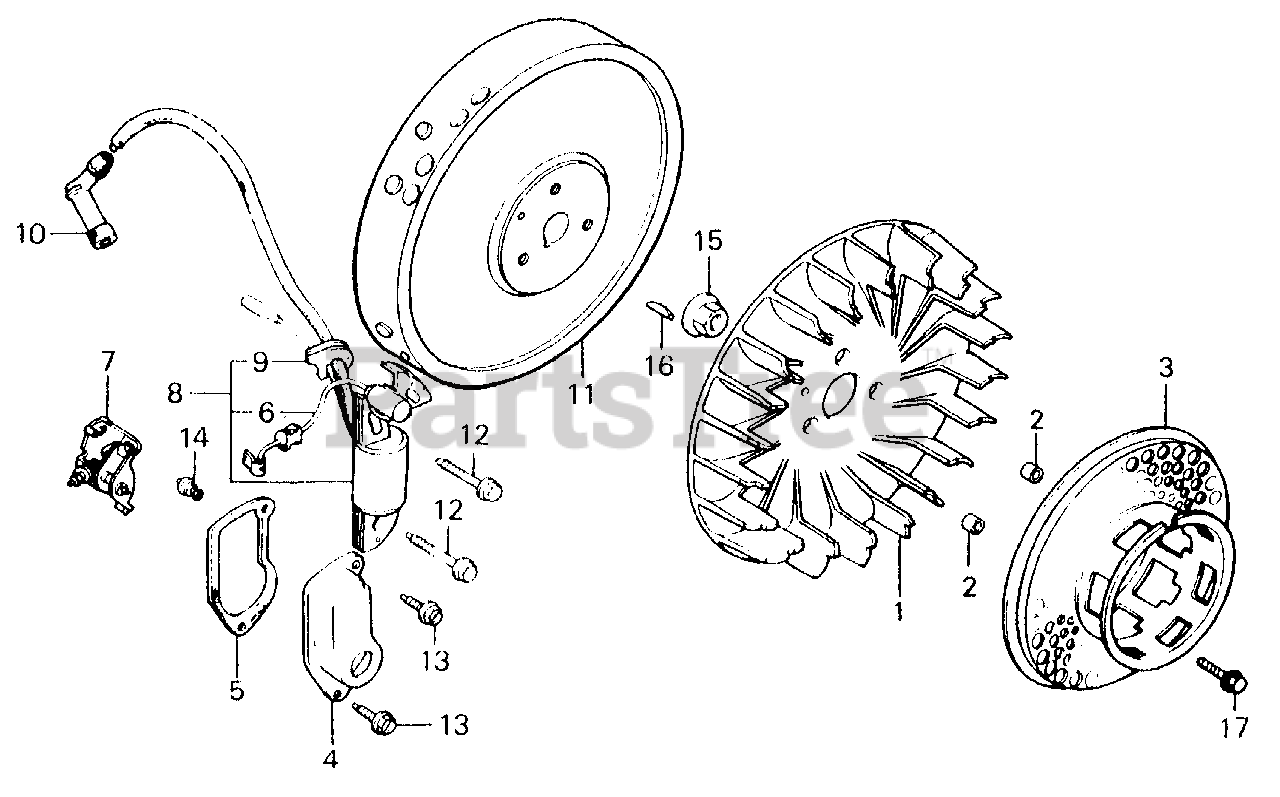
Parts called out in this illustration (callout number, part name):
1	FAN, COOLING
2	COLLAR, FAN
3	PULLEY, STARTER
4	COVER, POINTS
5	GASKET, POINT COVER
6	CONDENSER
7	POINTS ASSY.
8	COIL ASSY., IGNITION
9	GROMMET, WIRE
10	CAP ASSY., NOISE SUPPRESSOR
12	BOLT, FLANGE (6X32)
13	BOLT, FLANGE (5X10)
14	SCREW-WASHER (5X12)
15	NUT, SPECIAL (14MM)
16	KEY, SPECIAL WOODRUFF (25X18)
17	BOLT, FLANGE (6X16)
